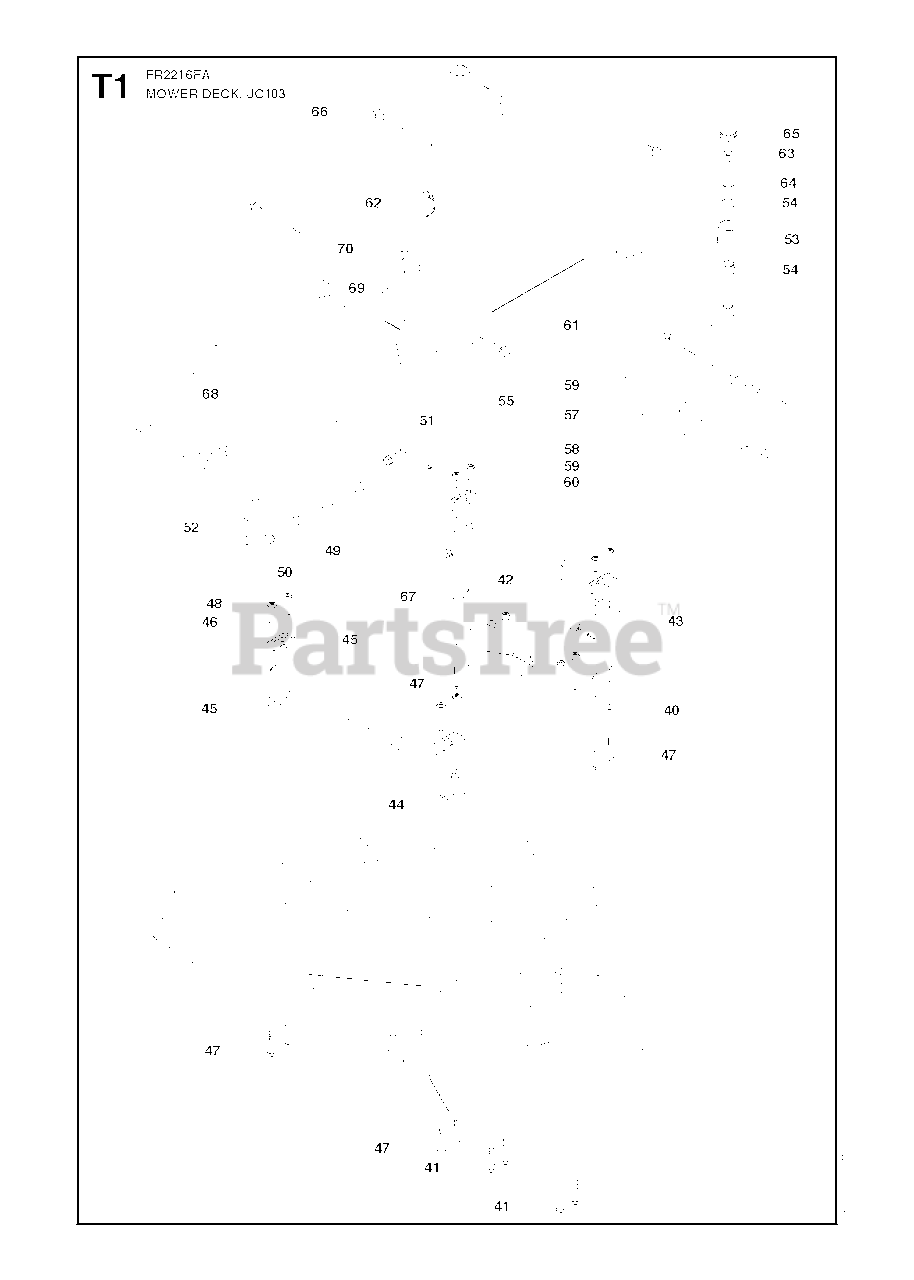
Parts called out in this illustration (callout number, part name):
42	LOCKNUT M8
48	LOCKNUT M8
49	PARALLELL ROD ASSY
50	PARALLEL ROD
51	RETAINER
52	SPLIT PIN
57	DECK ROLLER, FRONT
58	PIPE
59	SPACER
61	NUT
62	CLIP GRAY
67	LOCKNUT M8
